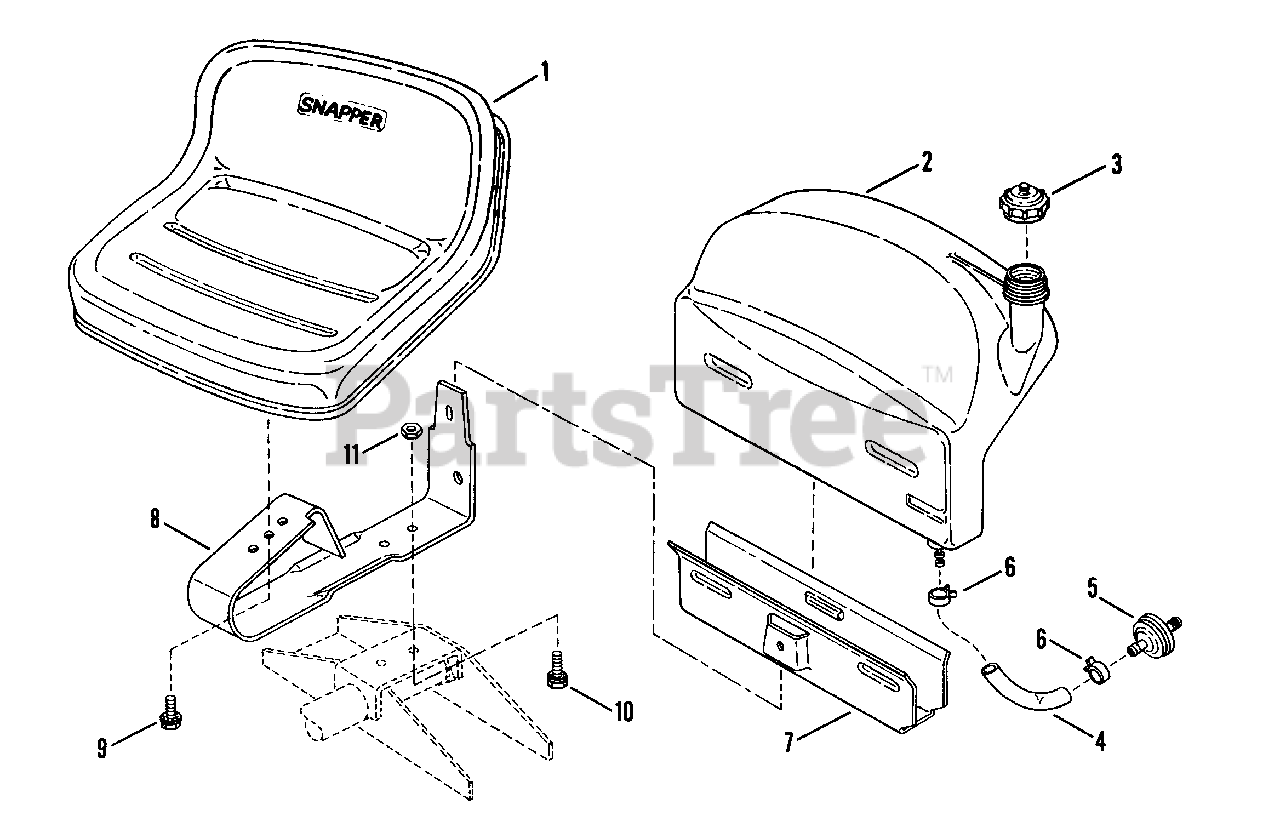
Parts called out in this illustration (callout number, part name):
1	SEAT, Operator
2	ASSEMBLY, Fuel Tank
3	CAP, Fuel Tank
4	HOSE, Fuel, 7"
5	FILTER, Fuel, In-Line
6	CLAMP, Fuel Line
7	BRACKET, Fuel Tank
8	SPRING, Operator's Seat
9	BOLT, 1/2-13x3/4" Hex Flange Lock
10	BOLT, 3/8x1" Hex Flange Lock
11	LOCKNUT, 3/8 Hex Flange
